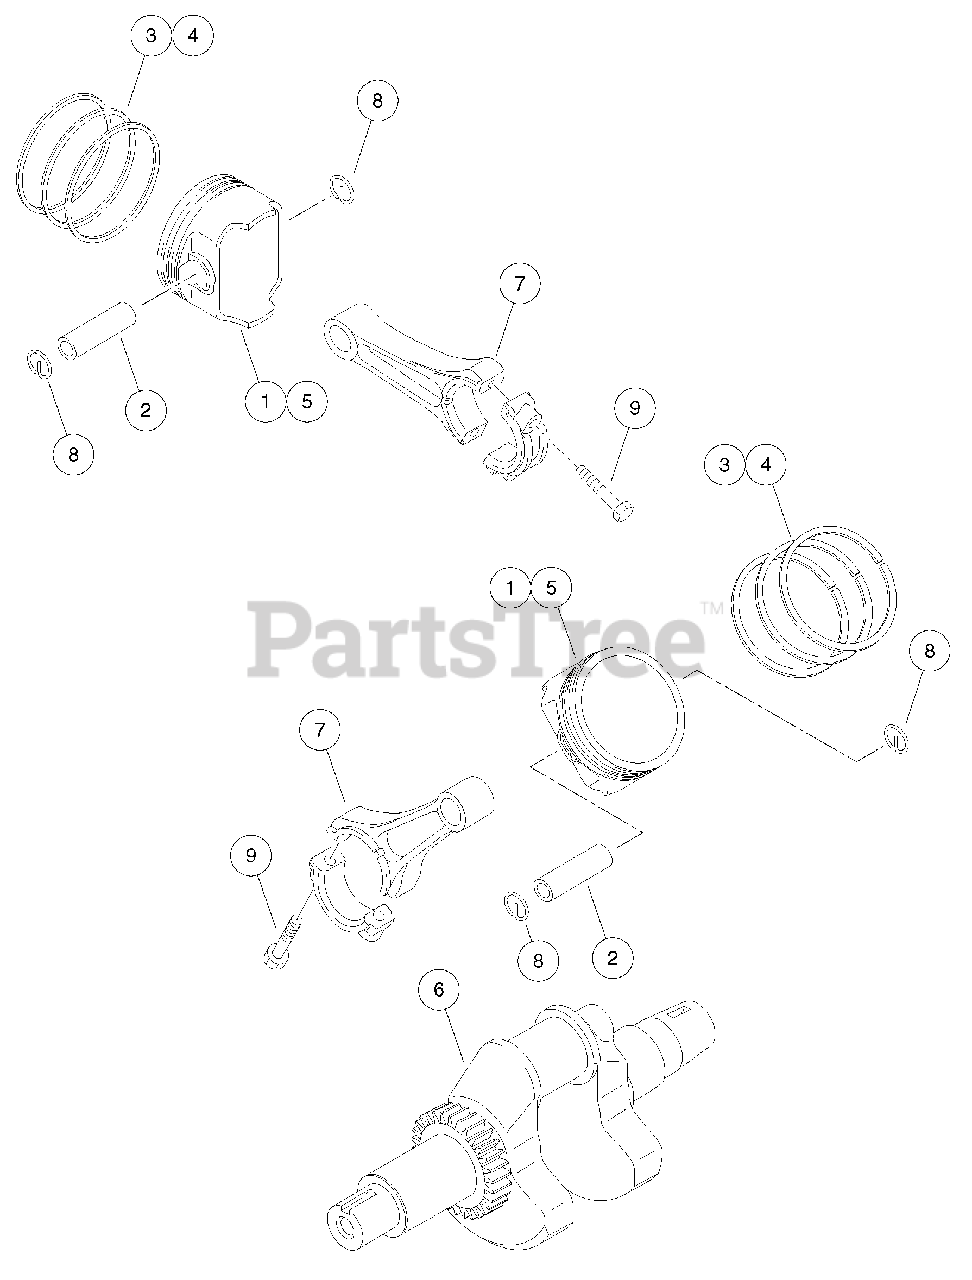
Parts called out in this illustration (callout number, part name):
1	Piston, Engine, Right, Fh
2	Pin, Piston, Engine, Fh
3	Ring, Set, Piston, Fh
4	Ring, Set, Piston L, 0.50, Fh
5	Piston, Engine L, 0.50, Fh
6	Crankshaft, Comp, Fh
7	Kit, Rod, Connecting, Fh
8	Ring, Snap, Pin, Piston, Fh
9	Bolt, Flg, M6 X 1.00 X 35
